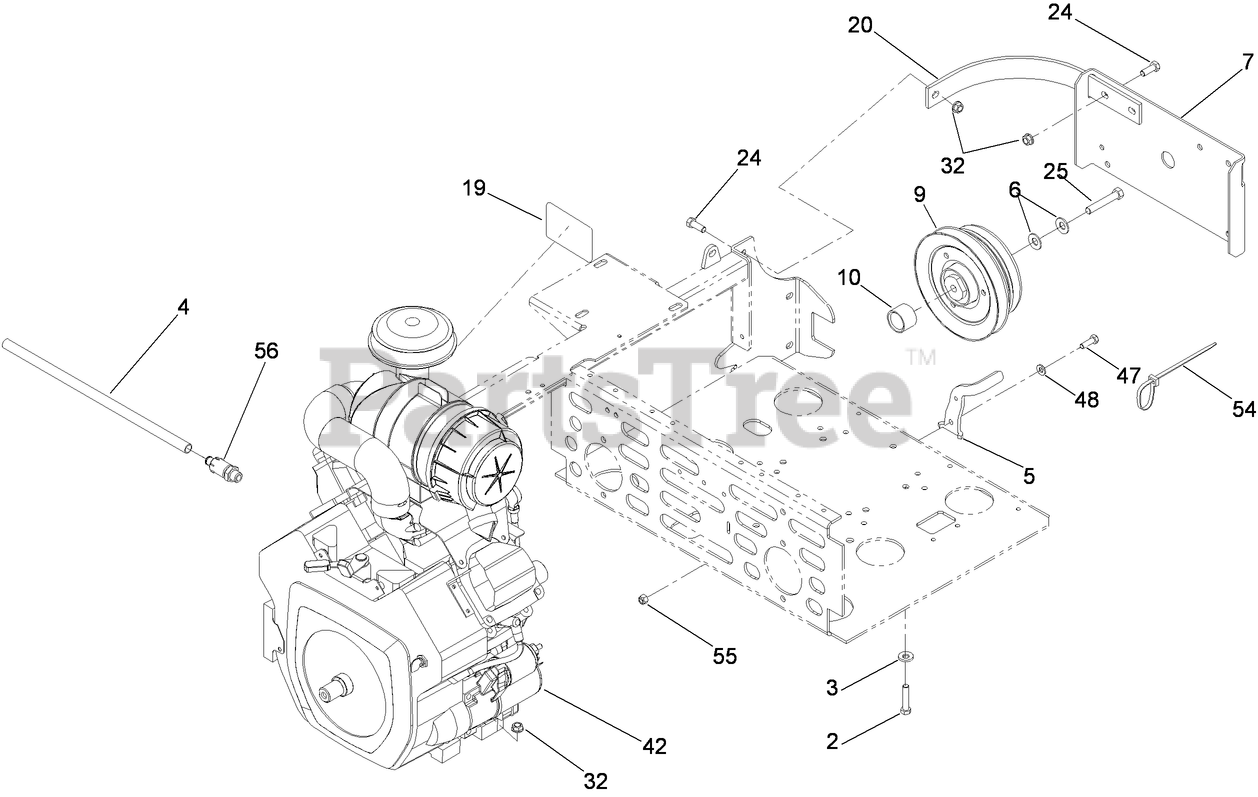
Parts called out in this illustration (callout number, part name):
2	SCREW-HH
3	WASHER-BELLEVILLE
4	TUBE-DRAIN, OIL
5	ANCHOR-CLUTCH
6	WASHER-SPRING
7	GUARD-CLUTCH
9	CLUTCH
10	SPACER-CLUTCH
20	STRAP-GUARD
24	SCREW-HH
25	SCREW-HH
32	NUT-HHF, WHIZ
47	SCREW-HH
48	WASHER-SPRING
54	TIE-PLASTIC
55	NUT-LOCK, NI
56	VALVE-DRAIN, OIL
